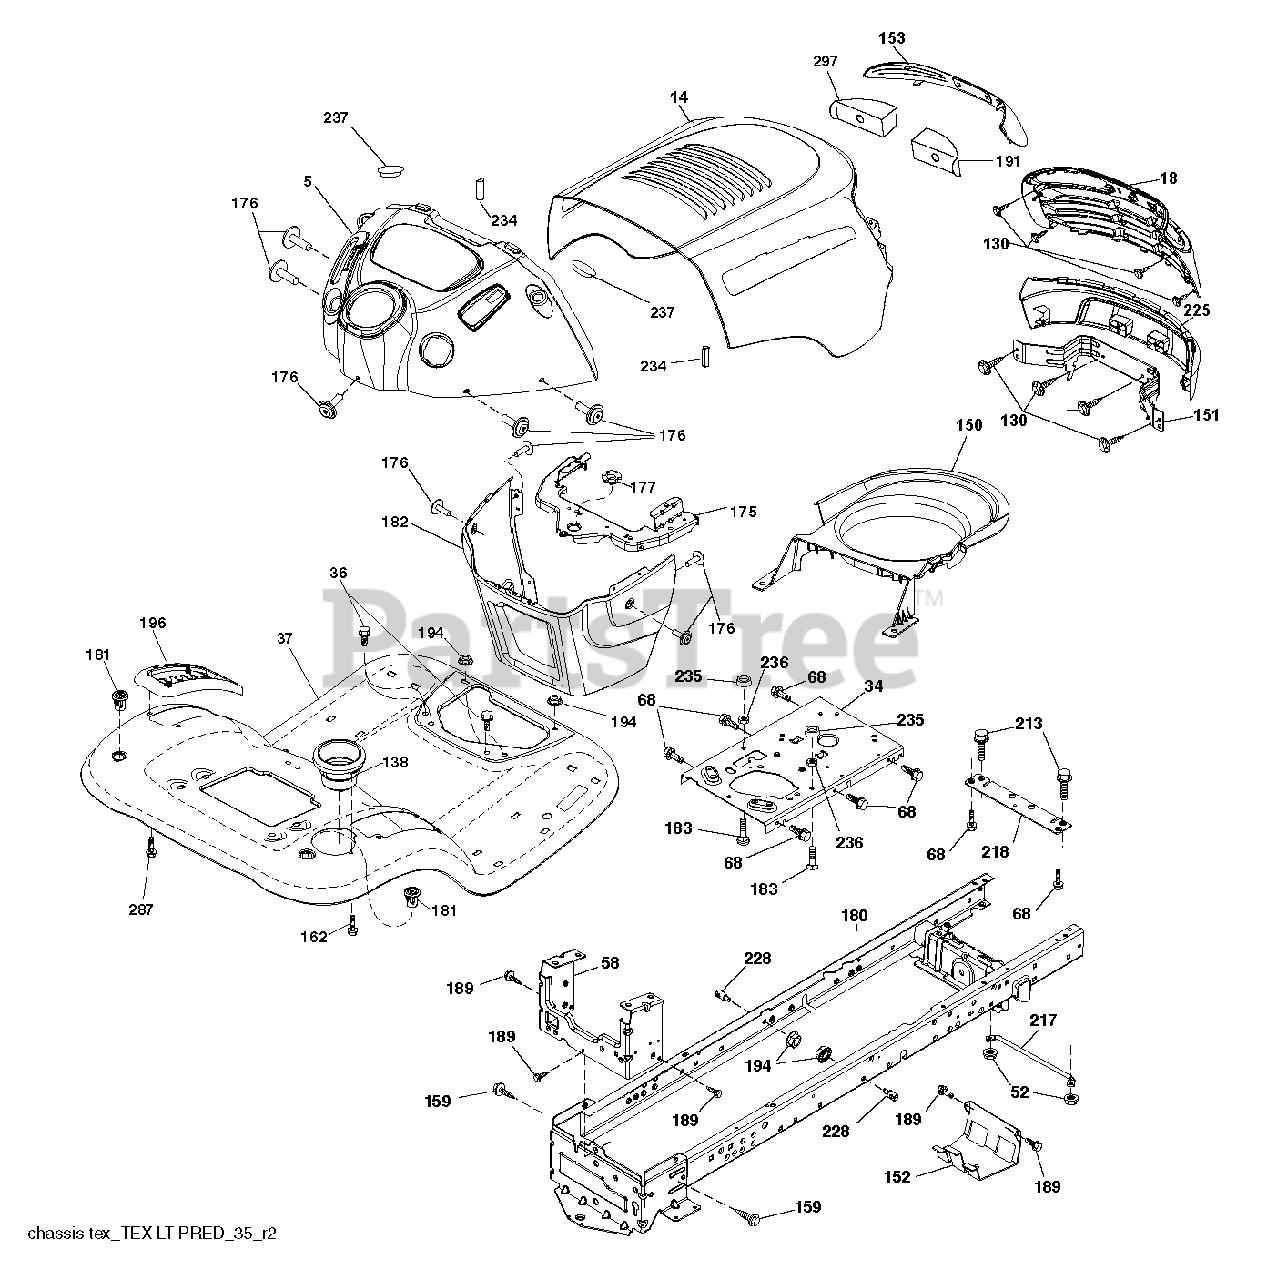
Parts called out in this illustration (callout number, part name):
5	DASH.PRED.LT.CC.ICY.N/SRV.BLK
14	HOOD.PREDATR.LT.U-FRM.TPVNT428
18	GRILL
34	PLATE.ENGINE.WELDED.CHASSIS
36	SCREW 5/16"
37	FENDER.TLT.W/CPH.428
52	LOCKNUT
58	DRAWBAR UPPER 2PC SMALL FENDER
68	SCREW LT
130	SCREW.#10 X 0.750.BOS (2 2)
138	CUPHOLDER.TL.TEX.BLACK
150	DUCT.AIR.TOP.VENT.PREDATOR.LT
151	BRACKET.PIVOT.ALPHA.LT
152	SHIELD.BROWNING.W/TEX
153	LENS.PREDATOR.LT.
159	SCREW, 3/8-16X3/4
162	SCREW.HI-LO.CONSOLE
175	CROSSMEMBER.LT
176	SCREW.#10-24X5/8.RN.QU
177	BUSHING STEERING
180	CHASS.WLDMNT.TL.12GA/2P.48/54
181	FEND/FTRST.PCH.CPH.NFW
182	DASH.LOWER.PREDATOR LT
183	BOLT.5/16-18X1-1/4 FULL THD
189	SCREW
191	INSERT.REFLECT.PREDATOR.LT.RH
194	NUT LOCK HEX FLANGE 5/16-18
213	BOLT
217	ROD.PIVOT.HOOD
218	X-PIECE.HOOD.STOP.NON/
228	STUD.FASTNER.W/ANTI-ROTATE
234	BUMPER.HOOD.TEX.HUSQVARNA
235	SPACER FENDER
236	NUT.CENTERLOCK.5/16-
237	PLUG.MOUNT.CARGO.BLK
287	SCREW 1/4X20
297	REFLECTOR.INSERT.PRED.LH.LT
